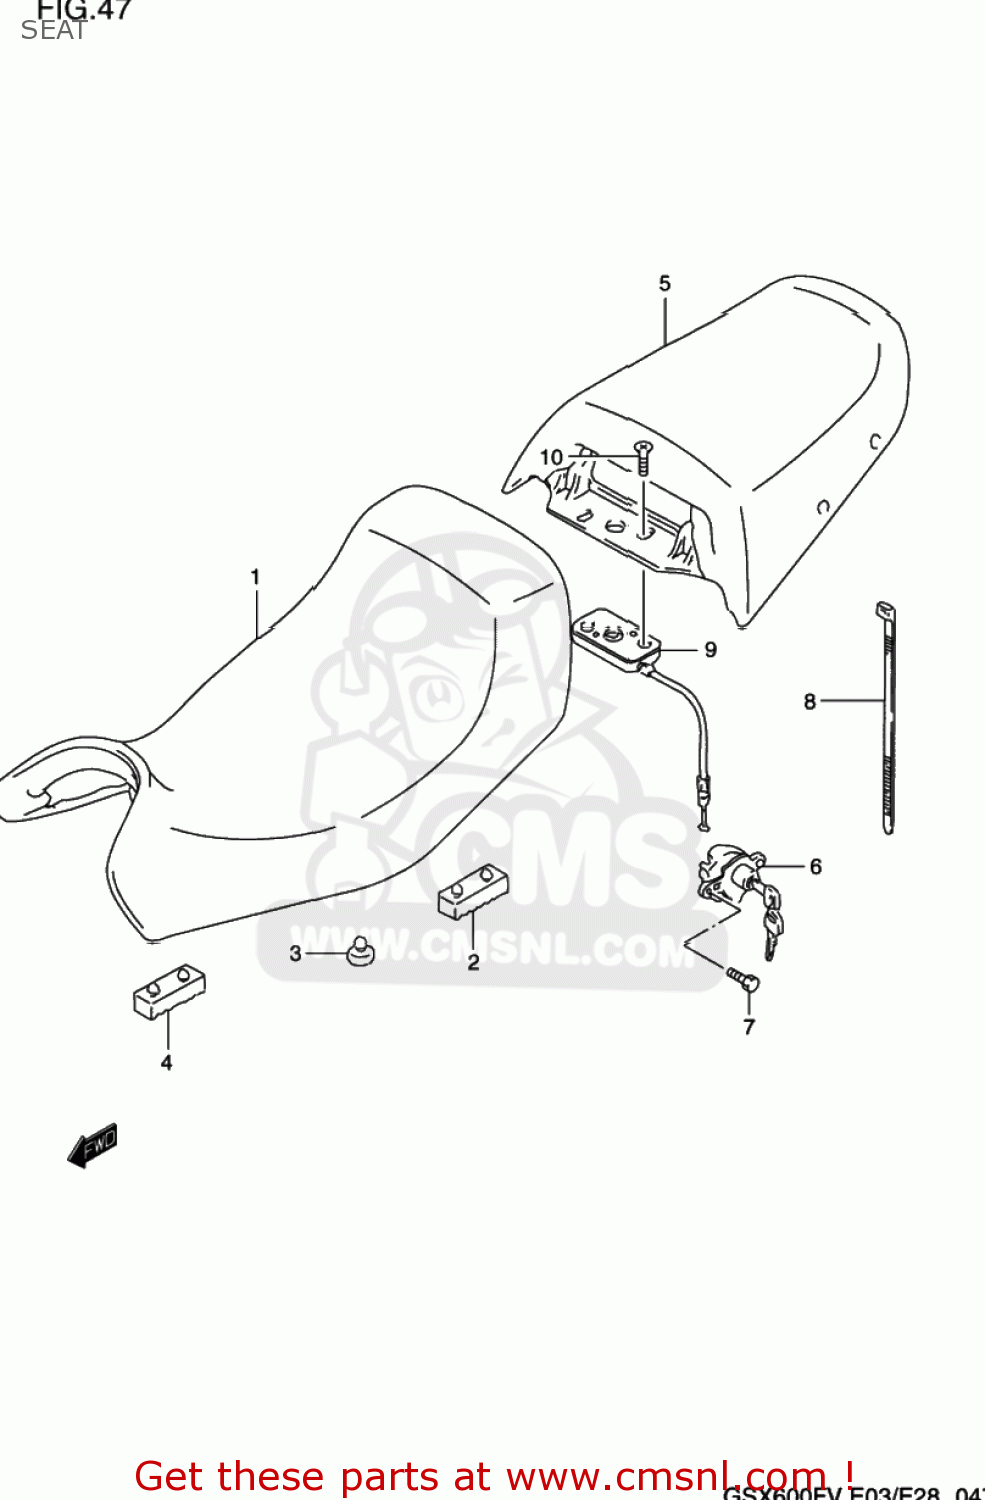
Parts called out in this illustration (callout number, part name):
1	SEAT SET
2	CUSHION,SEAT
3	CUSHION
4	CUSHION,SEAT(40X20X15)
5	SEAT SET,PILLION
6	LOCK SET,SEAT
7	BOLT
8	CLAMP L:165
9	BRACKET,SEAT SUPPORT RR
10	SCREW
